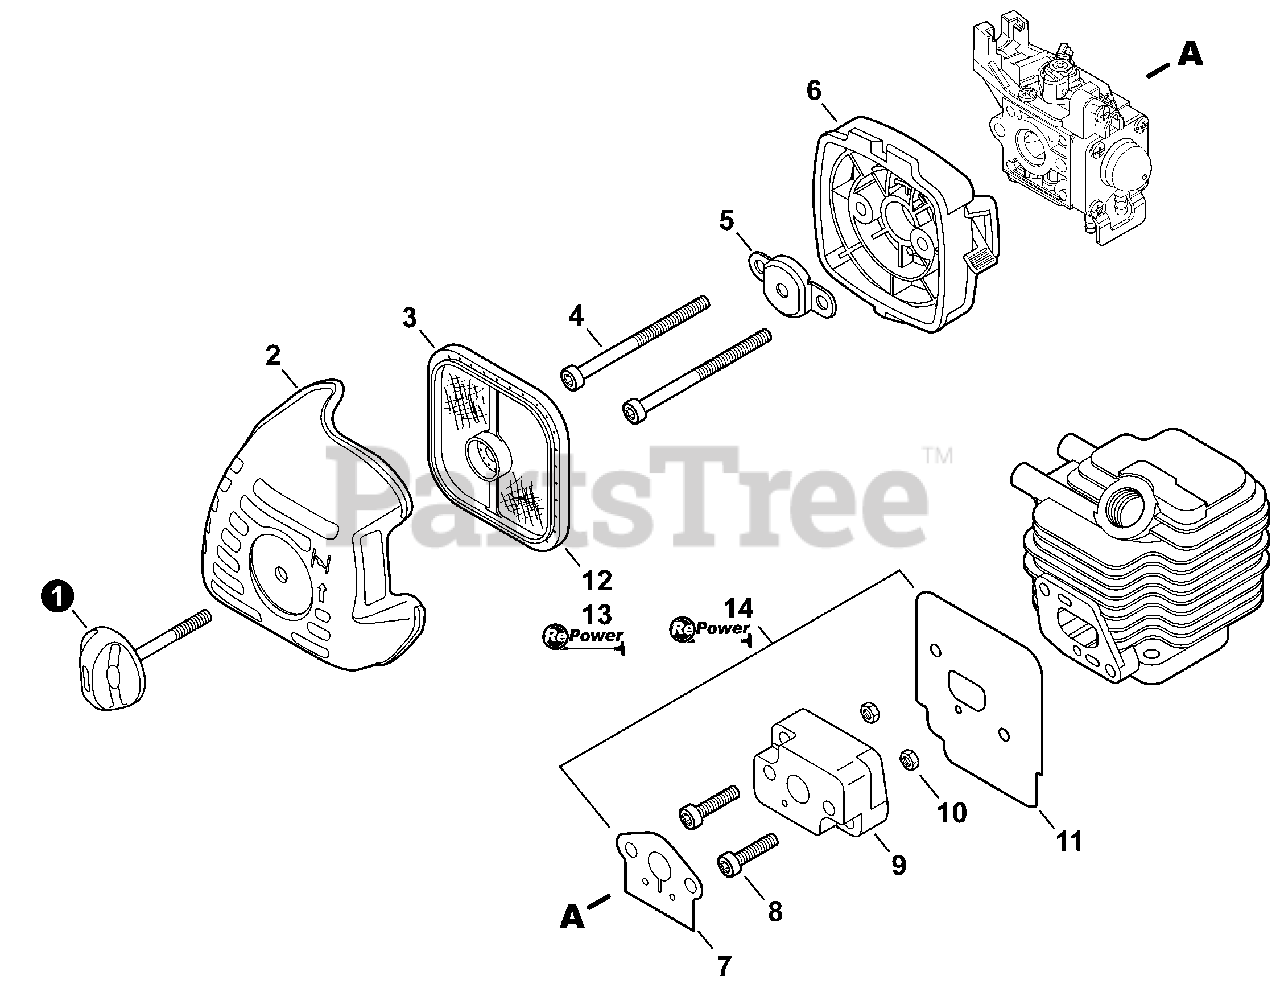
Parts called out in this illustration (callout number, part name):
1	THUMBSCREW
2	COVER, AIR FILTER
3	FILTER, AIR - DOUBLE LAYER
4	BOLT, TORX 5×65
5	PLATE, PREVENT
6	CASE ASSY, AIR FILTER
7	GASKET, INTAKE
8	BOLT, TORX 5×20
9	INSULATOR, INTAKE
10	NUT M5
11	HEAT SHIELD, INTAKE
12	TUNE-UP KIT - REPOWER
13	FILTER KIT - REPOWER
14	GASKET KIT: ENGINE, INTAKE, EXHAUST
